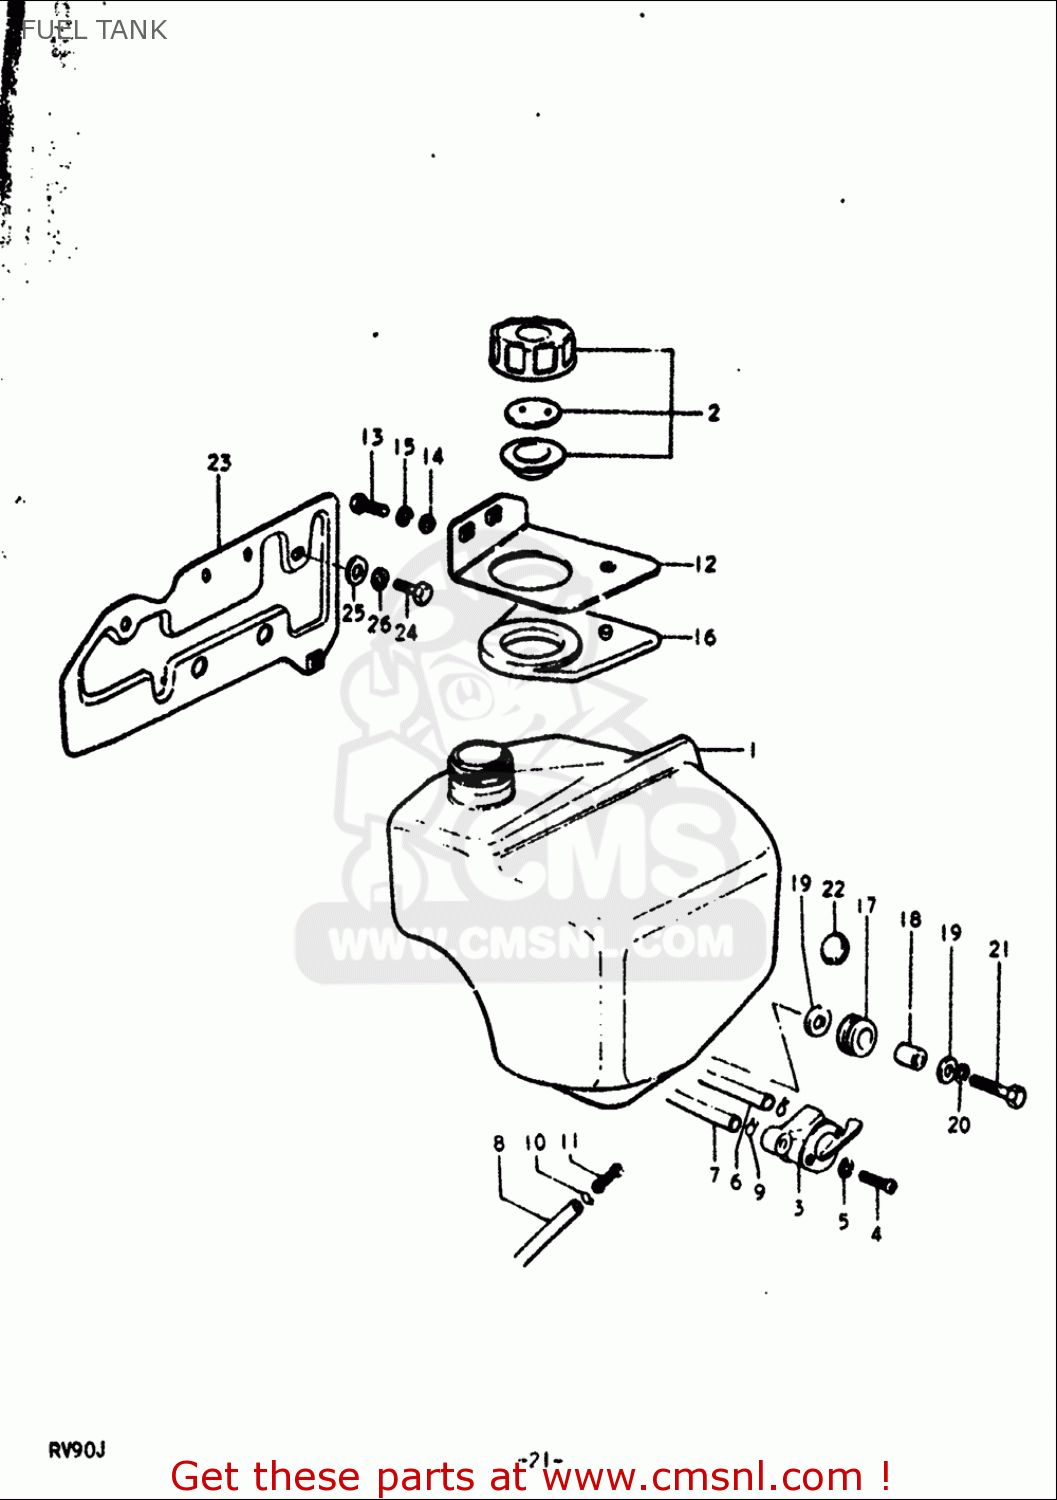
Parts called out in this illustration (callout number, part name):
2	CAP SET,FUEL TANK FILLER
3	COCK ASSY,FUEL
4	SCREW
5	WASHER,LOCK
8	HOSE(5X8.2X2000)
9	CLIP
10	CLIP
11	FILTER,FUEL
13	BOLT
14	WASHER
15	WASHER,LOCK
17	CUSHION
18	SPACER(8.5X12X13.5)
19	WASHER (8.5X30X2.3)
20	WASHER,LOCK
21	BOLT
22	CUSHION
24	BOLT
25	WASHER(6.5X16X1.2)
26	WASHER,LOCK
